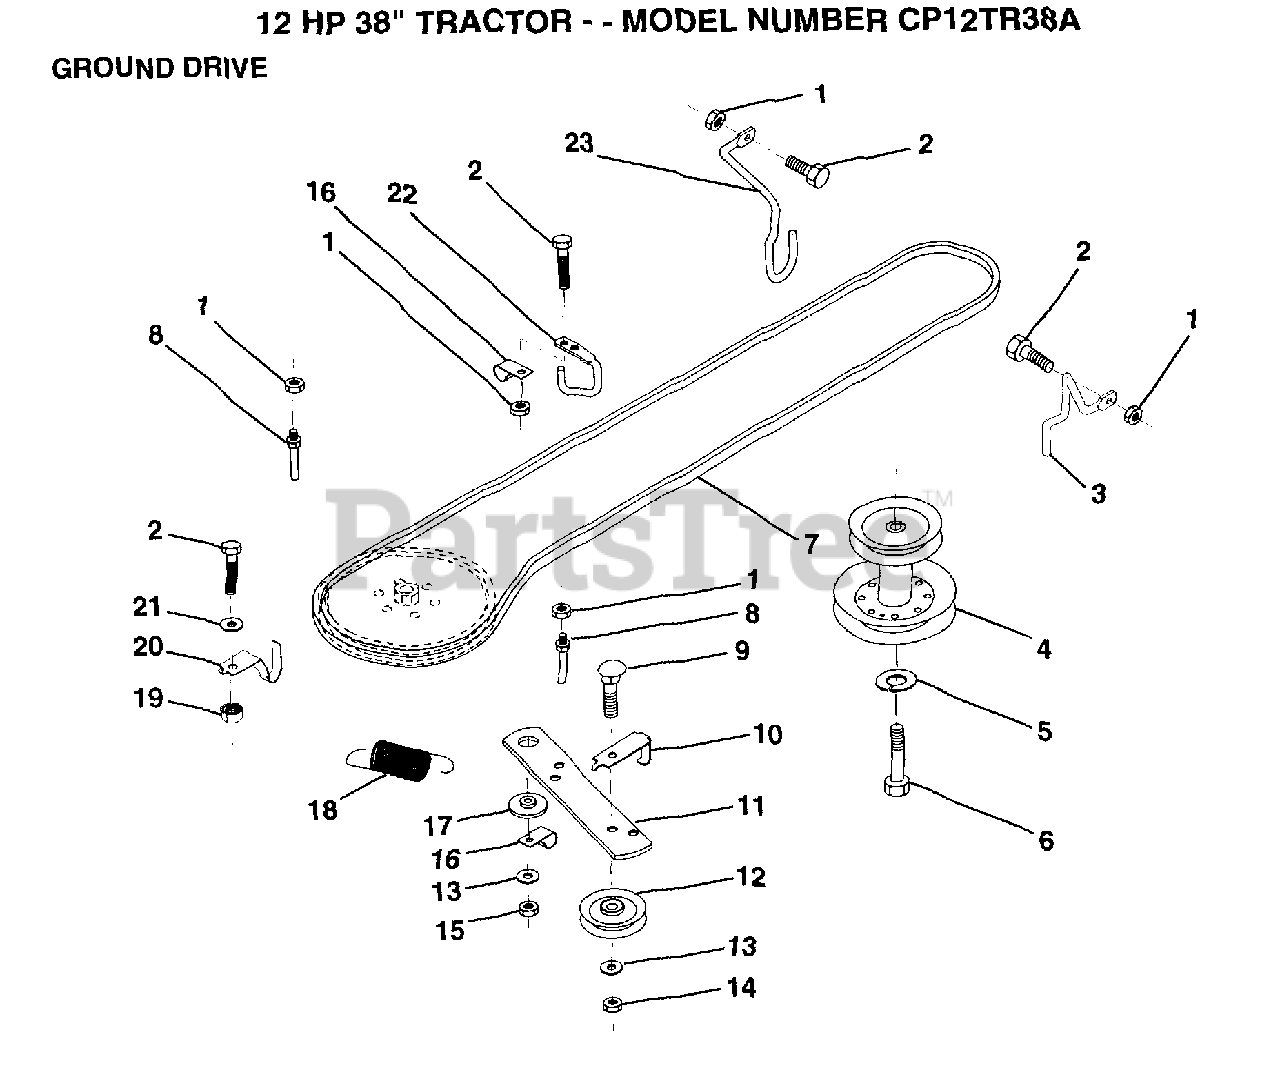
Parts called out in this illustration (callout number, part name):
1	NUT
2	BOLT
3	KEEPER.BELT.FRT.
4	PULLEY.ENGINE.LR
5	LOCKWASHER
6	HEX BOLT
7	BELT
8	"KEEPER,DRIVE BELT"
9	BOLT
10	"KEEP,IDLER DR BEL"
11	ARM IDLER CLUT GD
12	PULLEY.IDLER.FLAT
13	WASHER
14	LOCKNUT
15	NUT
16	CLIP INSULATOR
17	SPACER RETAINER
20	KEEPER.BELT.T/A
21	WASHER
22	"KEEPER,FRA DR BEL"
23	KEEPER.BELT.FRT.L
